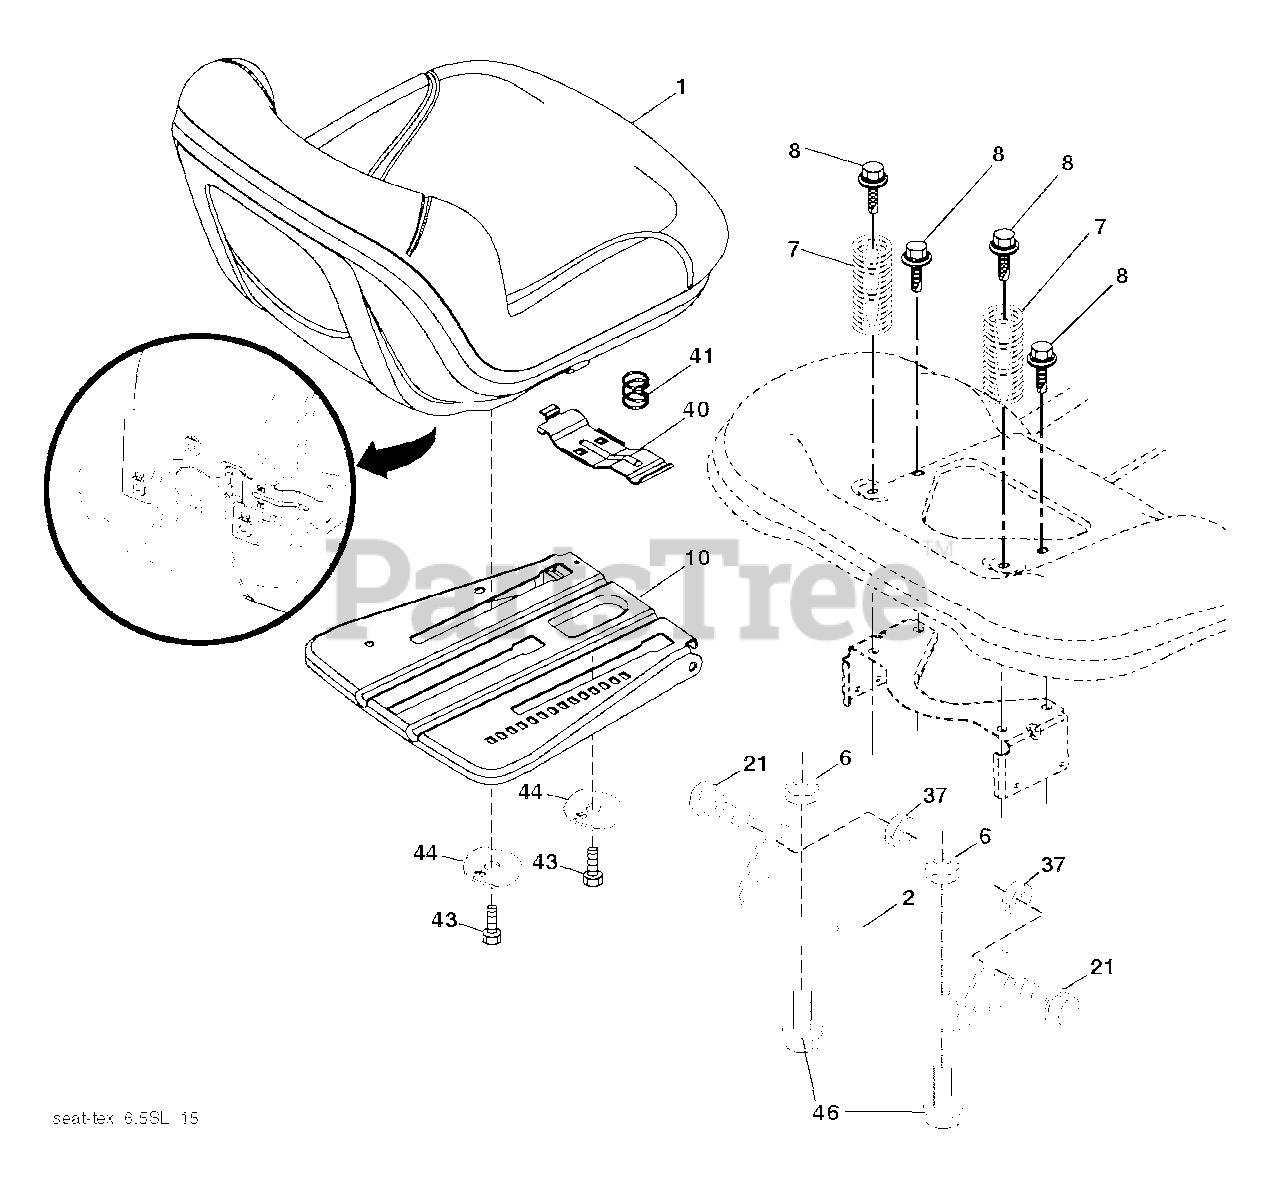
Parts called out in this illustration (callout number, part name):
1	SEAT.TH130.GREY.HUSQ.TEX
2	BRKT.PIVOT.FENDER
6	NUT
7	SPRING.COMPRESS.SEAT.
8	BOLT, 5/16-18 X 1 3/4
10	Seat Slide Plate, Pnt
21	BOLT.5/16-18X5/8.SHOULDER
37	NUT.71038.31-18.HEX.NYLOCK
40	HANDLE.SLIDE.SEAT.TEX.BLACK
41	SPRING.LATCH.SEAT.TEX
44	Winged Washer, 38Id 1
46	BOLT.3/8-16X1;1.25OD.WSHR.SEMS
